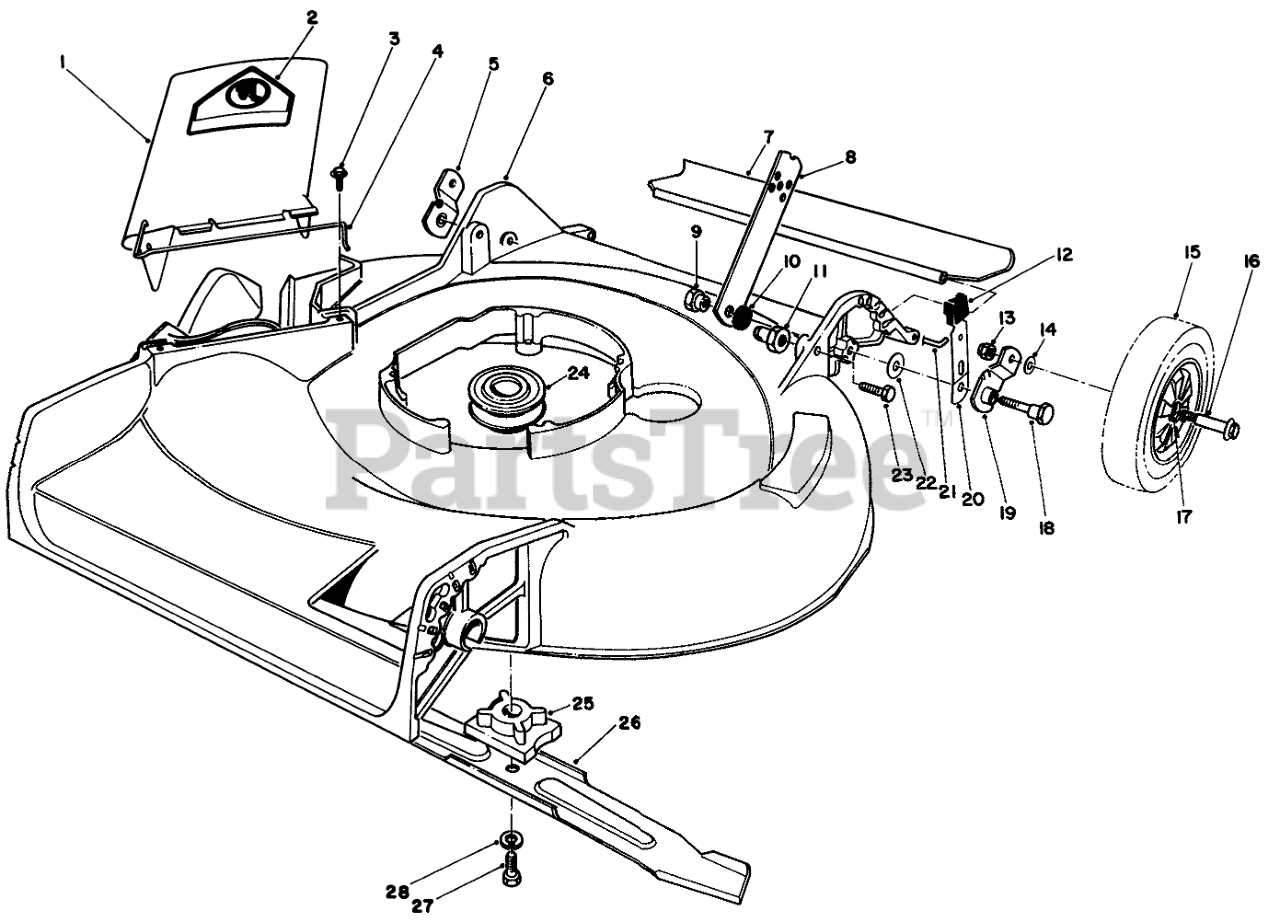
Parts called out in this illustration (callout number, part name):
1	Deflector Assembly (Incl. Ref #2 & 4)
2	DECAL-DANGER
3	SCREW-HWH
4	SPRING HINGE
5	Pivot Arm
6	Housing
7	REAR SAFETY SHIELD 21
8	HANDLE LATCH
9	HANDLE PIVOT NUT
10	SPACER
11	HANDLE PIVOT NUT
12	KNOB-ARM
13	Nut
14	WASHER
15	Wheel & Tire Assembly (Inc. Ref. #17)
16	BOLT-WHEEL
17	BUSHING
18	PIVOT SCREW
19	Pivot Arm
20	SPRING ARM ASM
21	SHIELD ROD
22	WASHER-PIVOT
23	SCREW-HH
24	Pulley
25	BLADE RETAINER
26	Blade
27	SCREW-HH
28	WASHER-LOCK
